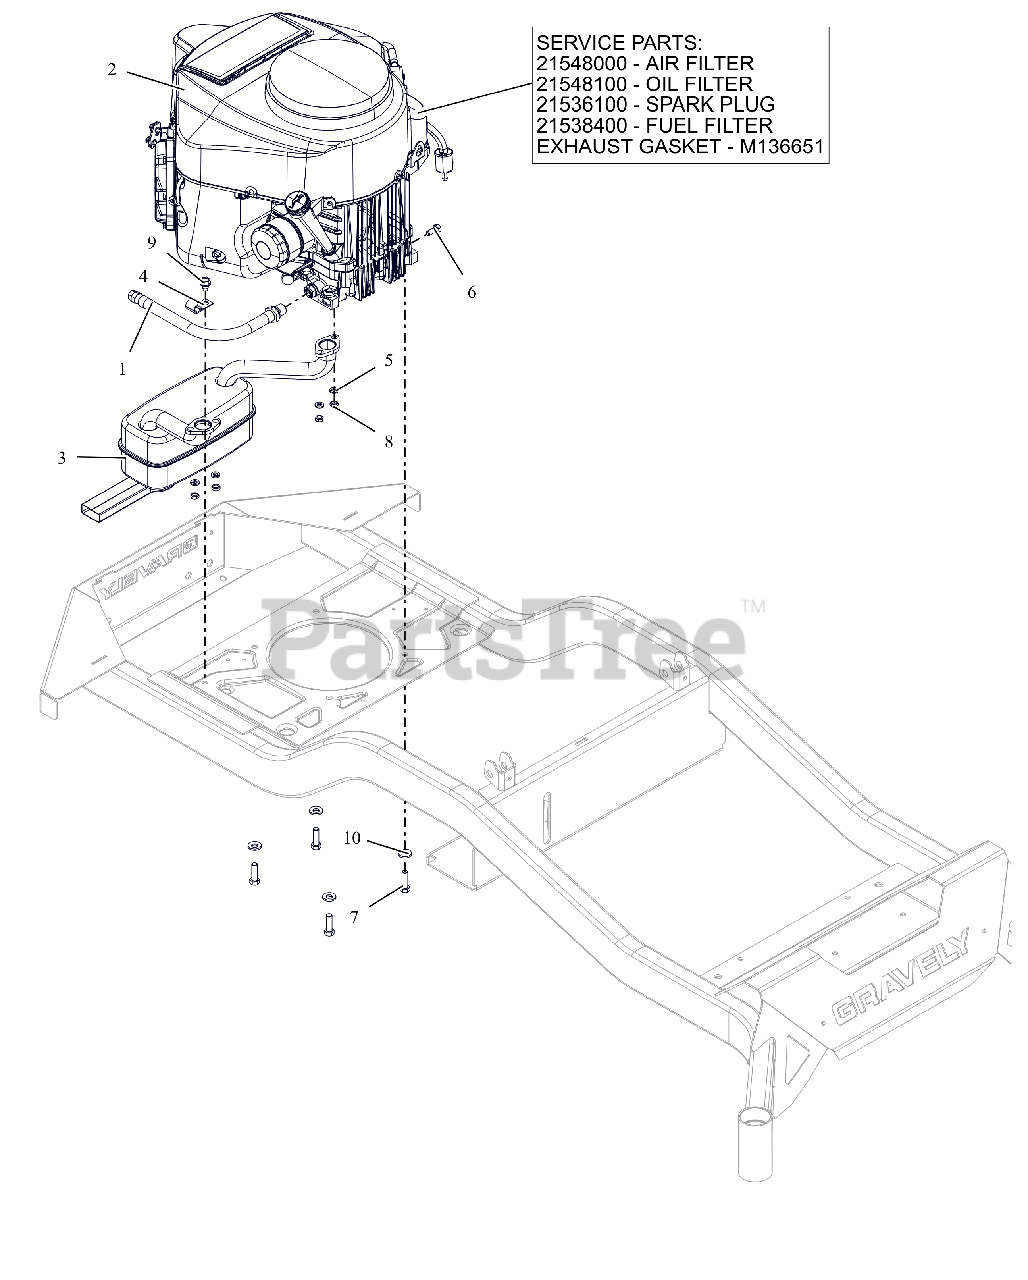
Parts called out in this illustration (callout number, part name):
1	HOSE, OIL DRAIN
2	ENGINE, KAWASAKI FR651V
2	AIR FILTER, KAWASAKI FR
2	OIL FILTER, KAWASAKI FR
2	PLUG, SPARK
2	FUEL FILTER - KAWASAKI
2	GASKET, MUFFLER #
3	MUFFLER, KAWASAKI
5	WSHR,LK-REG .312X.078 ZCC
6	BLT, HEX M8-1.25X20 G8.8 ZCC
7	BLT, HEX .38-16X1.25 G5 ZCC NT
8	NUT,NYL M8-1.25 G8.8 ZCC
9	SCR,TAP .375-16X.50 HWH TR ZCC
10	WASHER, 3/8" SPRING DISC
